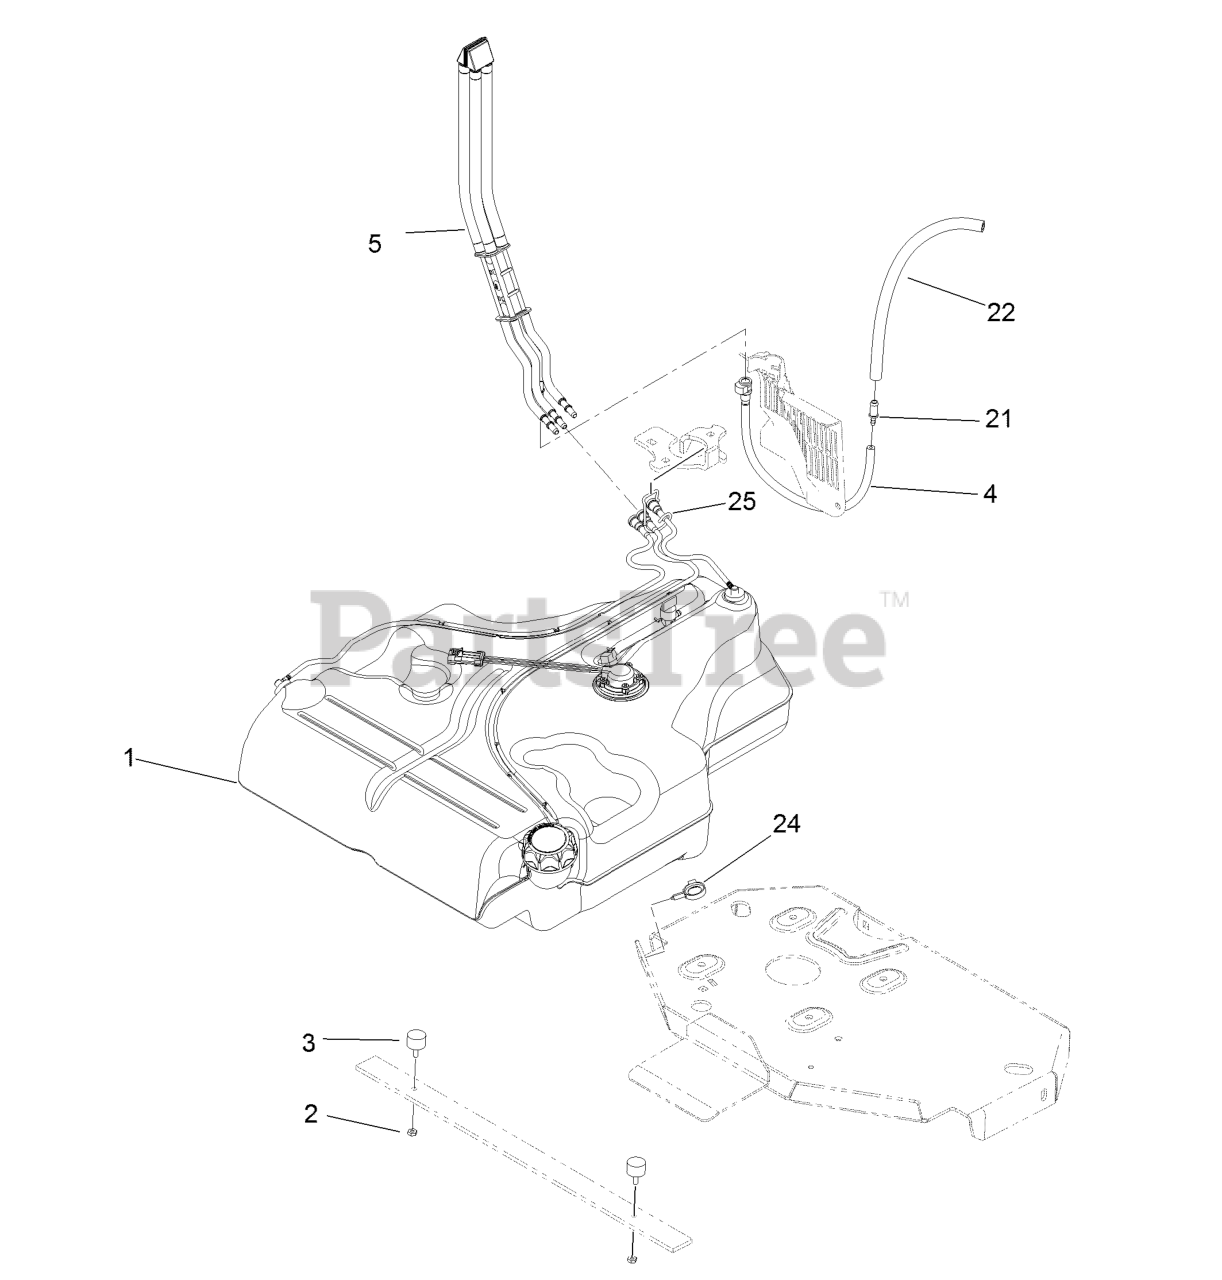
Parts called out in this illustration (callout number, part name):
2	NUT-JAM
4	HOSE ASM
5	FUEL MANIFOLD VENT ASM
21	FITTING-STRAIGHT
22	HOSE-FUEL
24	CLAMP-HOSE
25	RETAINER-LINE, VAPOR
